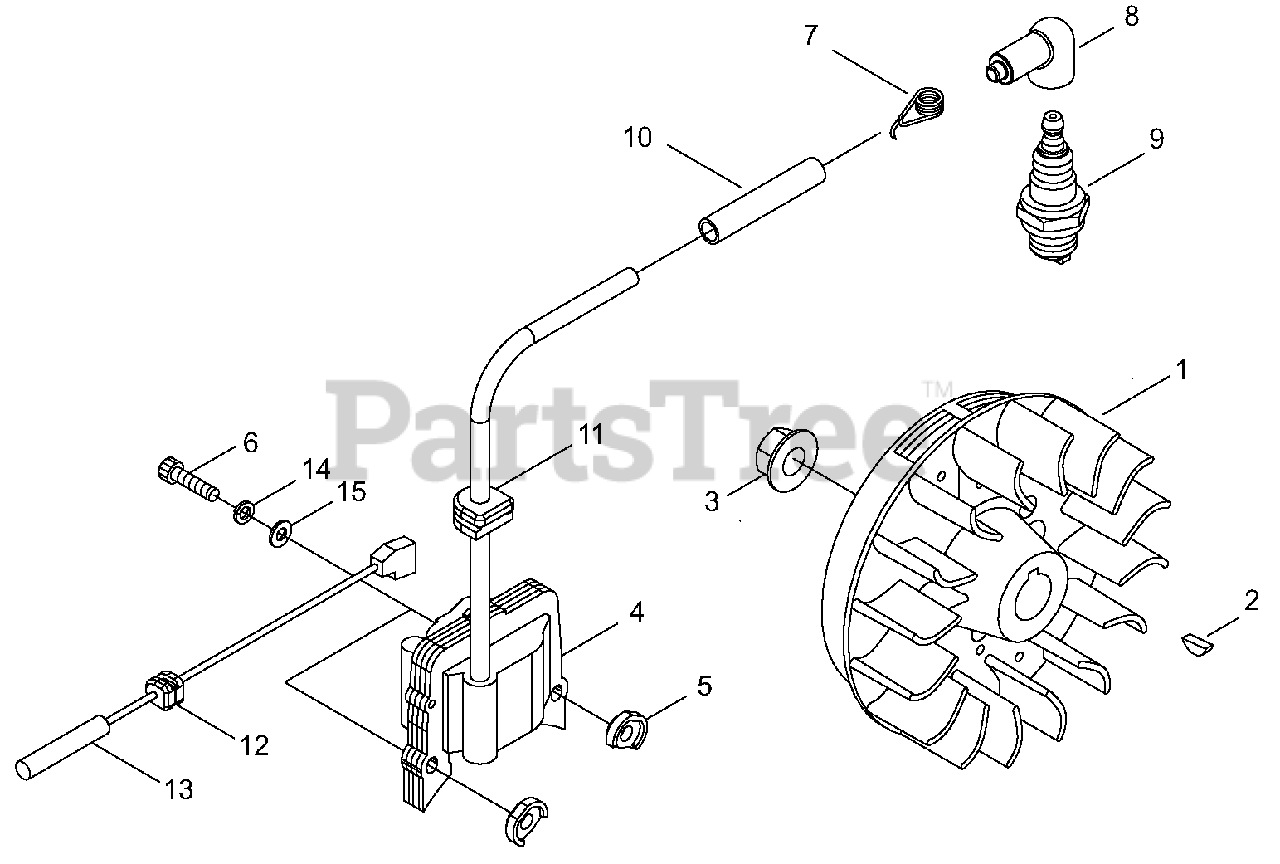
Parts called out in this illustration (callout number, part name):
1	FLYWHEEL
2	KEY - 3X10
3	NUT - FLANGE
4	COIL, IGNITION
5	LEAD - IGNITION
6	TUBE
7	GROMMET
8	GROMMET
9	CAP, SPARK PLUG
10	TERMINAL, SPARK PLUG CAP
11	INSULATOR
12	BOLT - 4X24
13	LOCKWASHER - 4
14	WASHER
15	SPARK PLUG -- CJ-8
